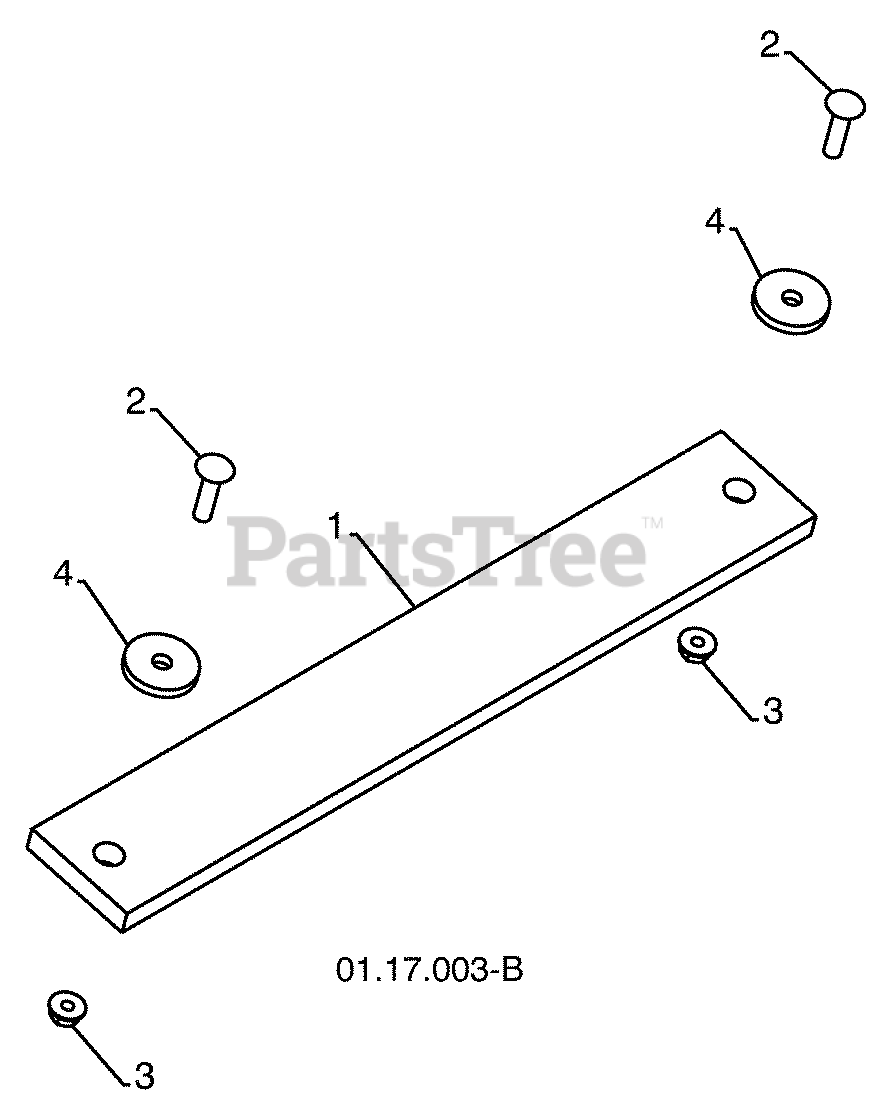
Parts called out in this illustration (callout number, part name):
1	WEIGHT BAR
2	CARRIAGE BOLT 5/16-18 X 1.25
3	NUT 5/16-18
